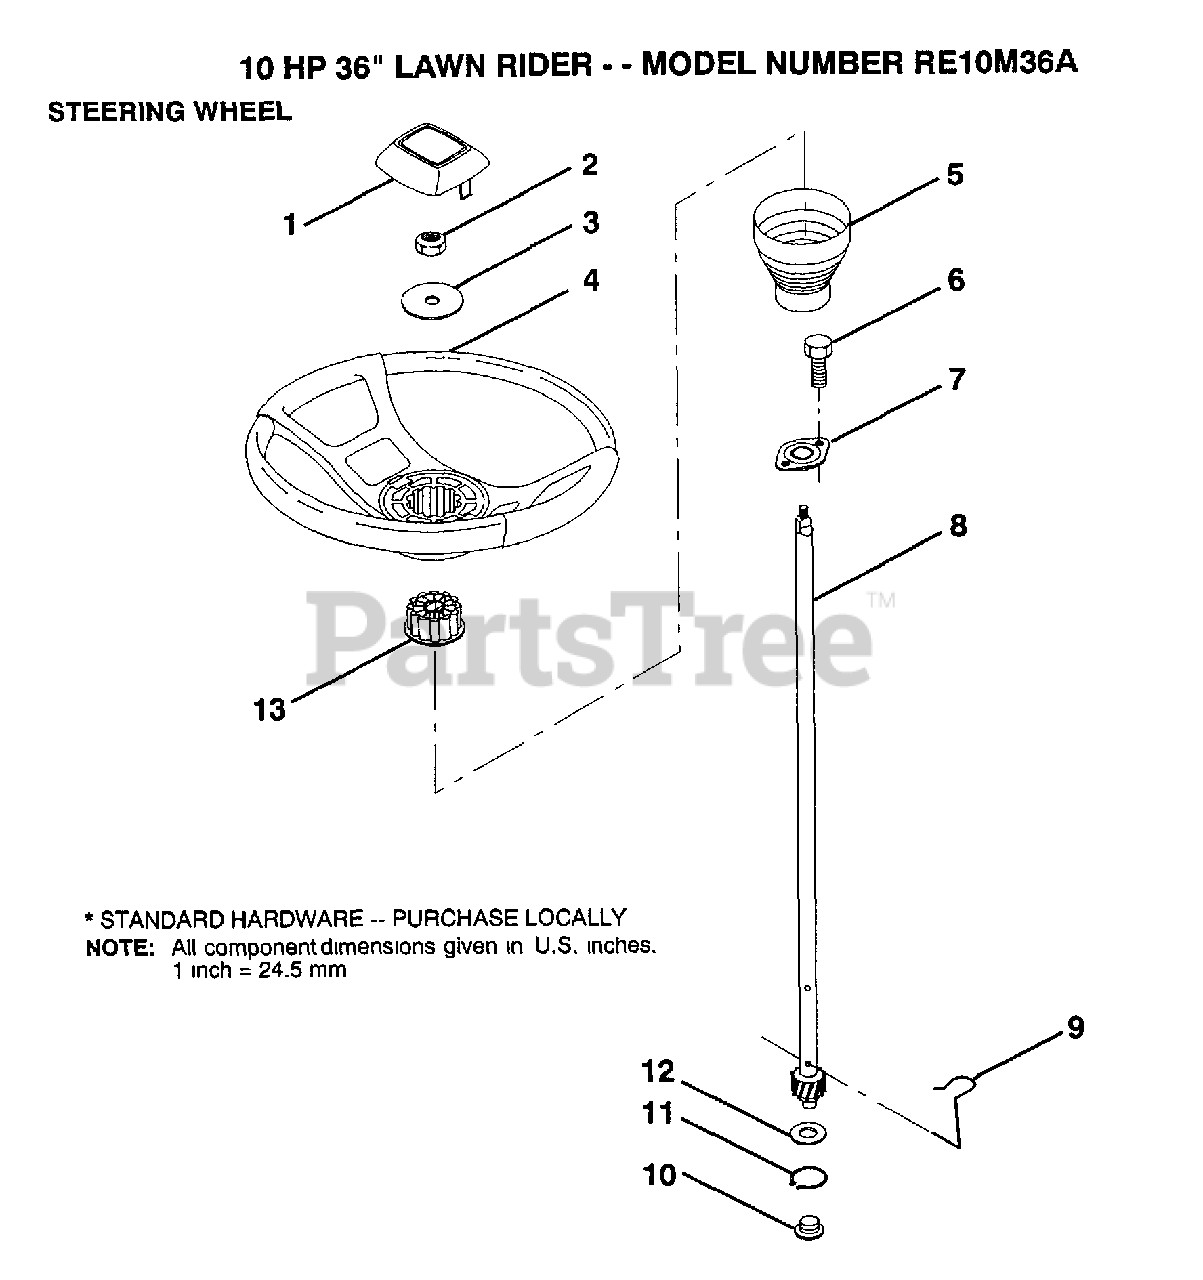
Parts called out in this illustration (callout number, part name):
1	ST WHL INSERT CAP
2	GRIPCO NUT
3	WASHER T
5	SLEEVE STEERING
9	STEERING CLIP
10	BUSHING STEER LWR
11	RING
12	WASHER LT
13	ADAPTER-WHEEL LT
